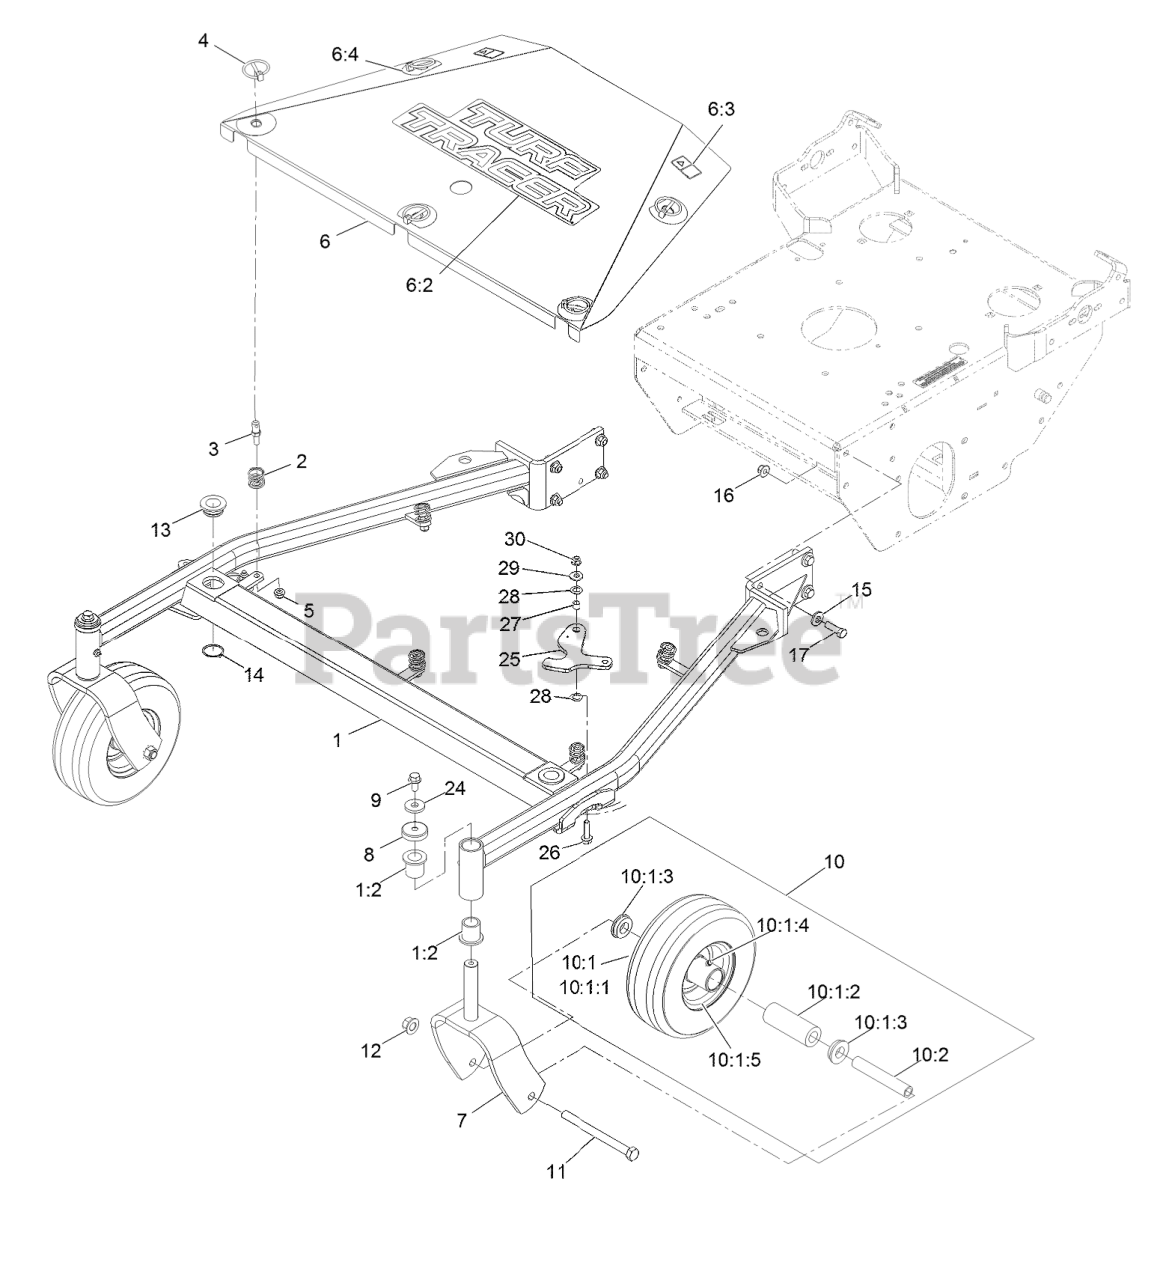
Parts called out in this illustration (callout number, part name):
1	ASM, FRAME W/ BUSHINGS, 4
1:2	BEARING-FLANGED
3	PIN-SPRING
4	PIN-LYNCH
5	NUT-HF, NI
6	ASM, SHIELD W/ DECALS, 48
6:2	DECAL-TURF TRACER
6:3	DECAL-WARNING
6:4	DECAL-SCRATCH COVER
7	FORK, CASTER
8	CAP, DUST
9	SCREW-HHF
10	KIT, SP CASTER WHEEL REPL
10:1	Wheel And Tire ASM
10:1:1	Tire
10:1:2	BEARING
10:1:3	BUSHING
10:1:4	FITTING-GREASE
10:1:5	Wheel
11	SCREW-HH
12	Nut-Lock 1/2-13
13	BUSHING-DECK
14	RING-RETAINING
15	WASHER-BELLEVILLE
16	NUT-HF, NI
17	SCREW-HH
